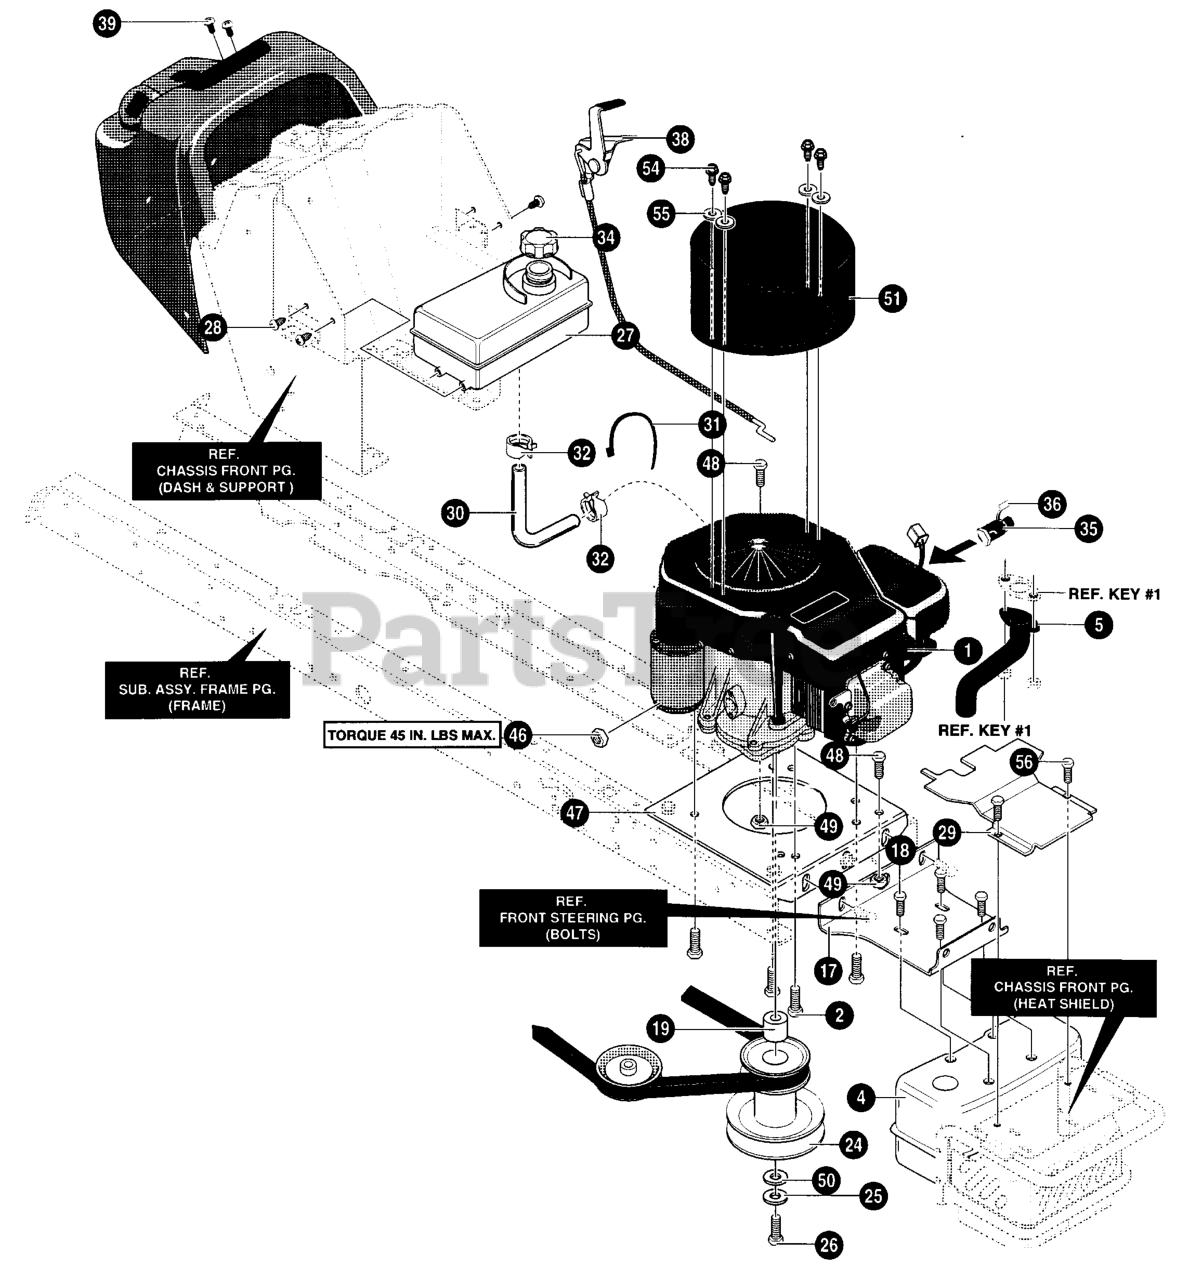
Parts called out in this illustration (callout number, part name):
1	ENGINE 15HP KOHLER
4	MUFFLER, SINGLE- CYLINDER
5	EXHAUST TUBE
17	BRACKET, MUFFLER MOUNT
19	SPACER, SLEEVE
24	PULLEY, STACK ASSY
27	TANK, FUEL 1.4 GAL.
29	HEAT SHIELD
30	LINK, FUEL
31	CABLE TIE
32	CLAMP, FUEL LINE
34	CAP, FUEL
35	OIL DRAIN
36	CAP, OIL DRAIN
38	THROTTLE CONTROL
39	SCREW, #8-16X.50
46	NUT 1/4-20
47	PLATE, ENGINE
48	SCREW, 5/16-18 x 0.75
49	NUT, 5/16-18
50	FLATWASHER
51	PLENUM, 15HP KOHLER
54	SCREW 10-16X0.5
55	WASHER, FLAT
56	SCREW 1/4-20X0.63
